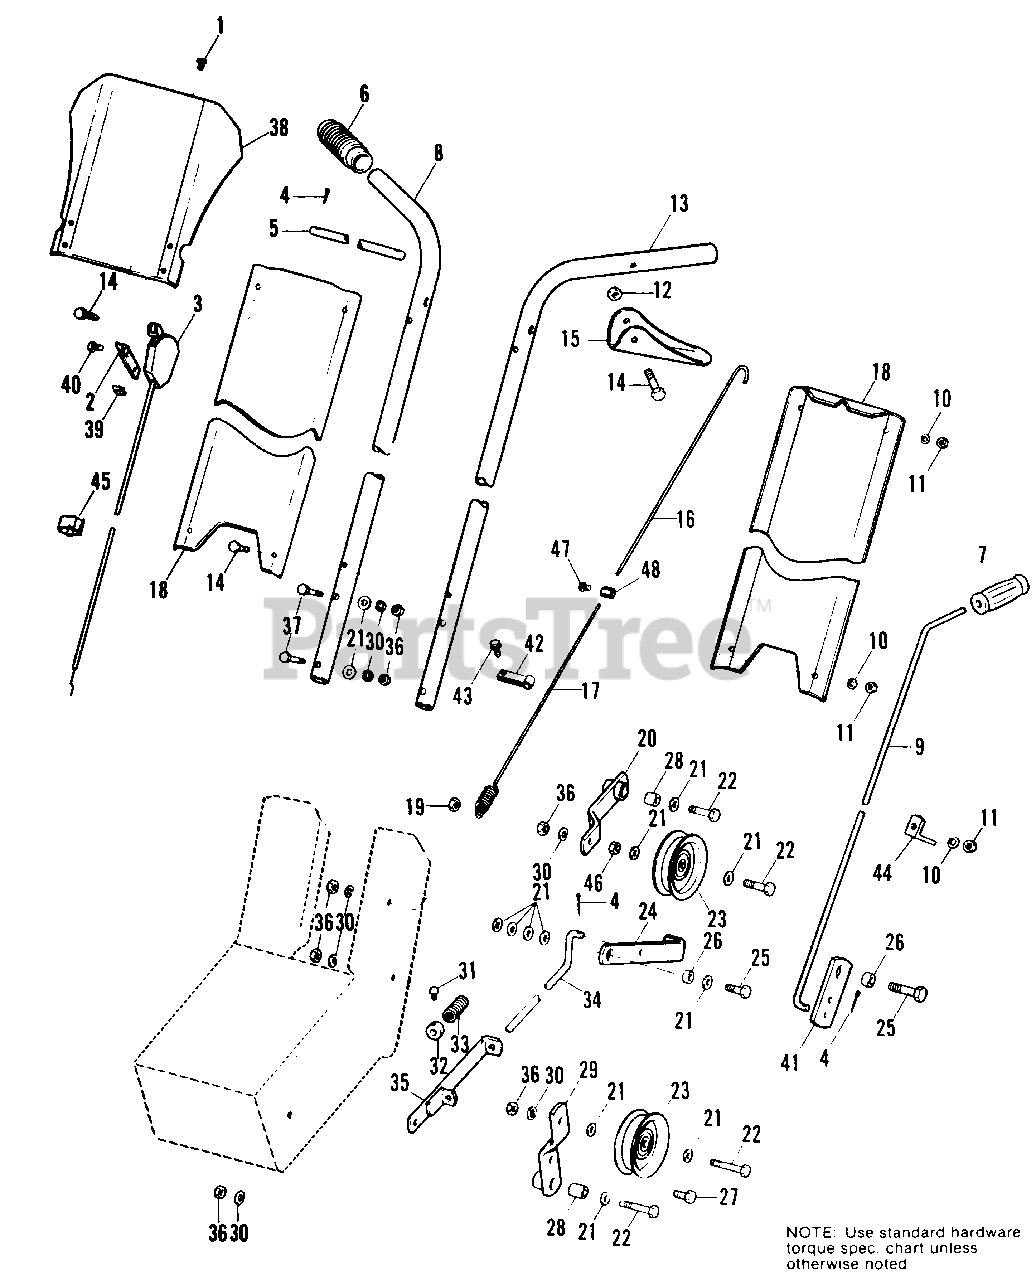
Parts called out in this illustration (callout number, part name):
1	SCREW, Hex, Self Tapping, #10-32 x 1/2
2	SUPPORT, Throttle Control
3	CONTROL ASSY., Throttle (990482 & 990483 Only)
3	CONTROL ASSY., Throttle (990558 & 990559 Only)
4	PIN, Cotter, 3/32 x 3/4
5	PIN, Lever
7	GRIP, Reverse Rod
8	HANDLE, R.H.
9	ROD, Reverse (990482 & 990483 Only)
9	ROD, Reverse (990558 & 990559 Only)
10	LOCKWASHER, 1/4
11	NUT, Hex, Full, 1/4-20
12	LOCKNUT, Hex, 1/4-20
13	HANDLE, L.H.
14	CAPSCREW, Hex, 1/4-20 x 1-1/2
15	GRIP, Clutch
16	EXTENSION, Wire
17	SPRING ASSY.
18	COVER, Handle
19	LOCKNUT, Hex, 3/8-16
20	LEVER ASSY., Idler
21	WASHER, Plain, 3/8
22	CAPSCREW, Hex, 3/8-16 x 1-3/4
23	PULLEY, Idler
24	PEDAL, Foot Clutch
25	CAPSCREW, Special
27	CAPSCREW, Hex, 3/8-16 x 7/8
28	BEARING, Race
29	LEVER ASSY., Idler
30	LOCKWASHER, 3/8
31	SETSCREW, Sq. Hd., 1/4-20 x 3/8
32	COLLAR, Set
34	ROD, Clutch
35	GUIDE ASSY., Rod
36	NUT, Hex, Full, 3/8-16
37	CAPSCREW, Hex, 3/8-16 x 2
38	HOUSING ASSY. (990482 & 990483 Only)
38	HOUSING ASSY. (990558 & 990559 Only)
39	SPEED NUT, Tinnerman
40	SCREW, Self Tapping, #10-24 x 1/2
41	BAR, Clutch
43	SCREW, Taptite, 1/4-20 x 3/8
44	CLIP, Spring
45	CLIP, Cable
46	LOCKNUT, Hex, Jam, 3/8-16
47	SCREW, Rd. Hd., #10-24 x 3/8
